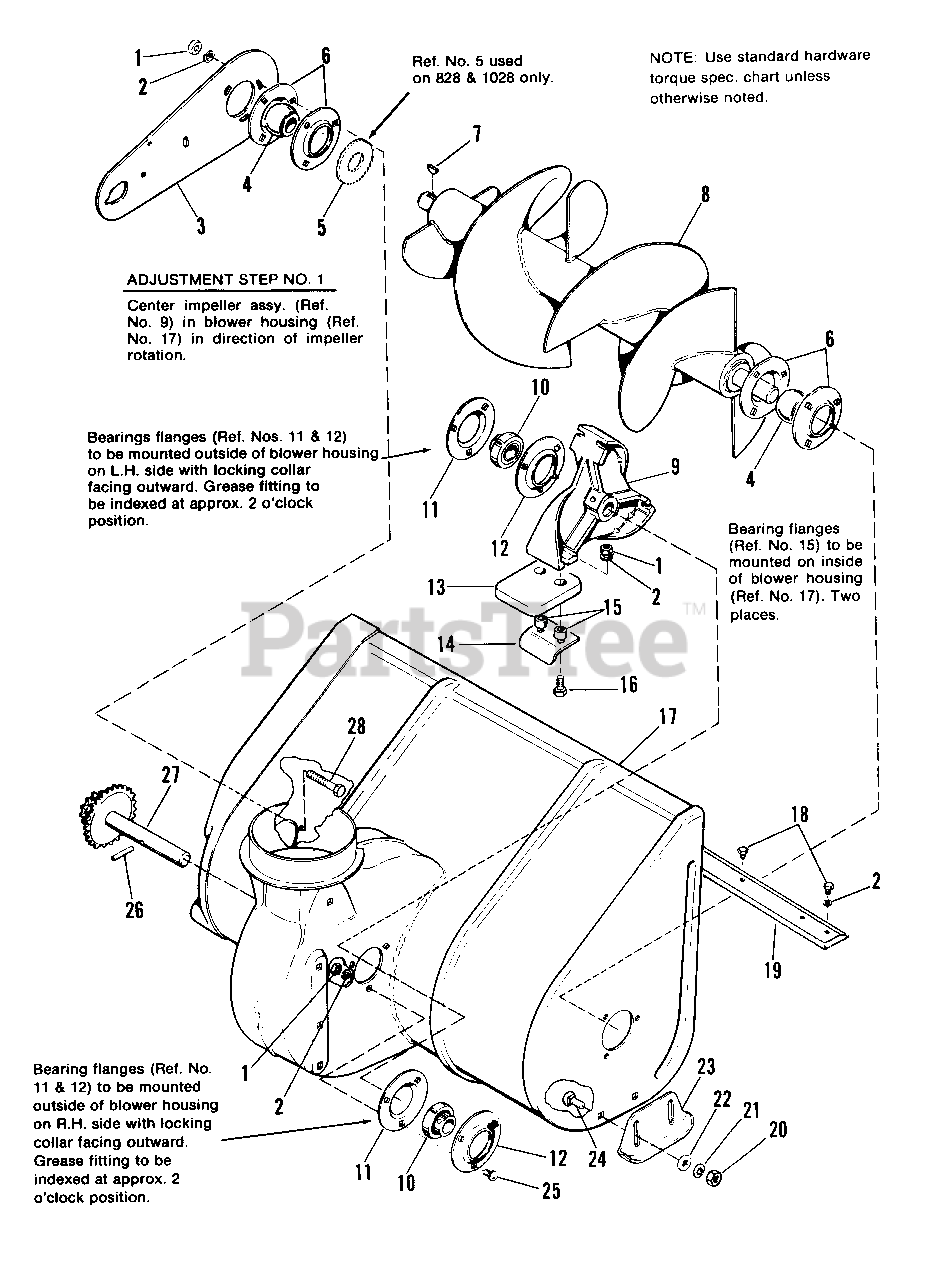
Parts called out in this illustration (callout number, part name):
1	NUT, Hex, Full, 5/16-18
2	LOCKWASHER, 5/16 (Qty. 26 on 524 & 724)
4	BEARING ASSY., Ball
5	PLATE (828 & 1028)
6	FLANGE, Bearing
7	KEY, Woodruff, #15, 1/4 x 1
8	ROTOR ASSY. (828 & 1028)
8	ROTOR ASSY. (524 & 724)
10	BEARING, Cartridge
11	FLANGE, Bearing
12	FLANGE, Bearing W/Fitting
13	BLADE, Impeller
14	PLATE, Backup
16	SCREW, Hex, Whiz, 5/16-18 x 1-1/2
17	BODY ASSY., Blower (524 & 724)
17	BODY ASSY., Blower (828 & 1028)
18	CAPSCREW, Hex Hd., 5/16-18 x 1/2 (Qty. 6 on 524 & 724)
19	SCRAPER, Body (524 & 724)
19	SCRAPER, Body (828 & 1028)
20	NUT, Hex, Full, 3/8-16
21	LOCKWASHER, 3/8
22	WASHER, Plain, 3/8
24	BOLT, Carriage, 3/8-16 x 3/4
25	BOLT, Carriage, 5/16-18 x 5/8
26	PIN, Spring, 5/16 x 1-7/8
27	SHAFT ASSY., Sprocket (Second Stage)
28	CAPSCREW, Hex Hd., 5/16-18 x 3/4
